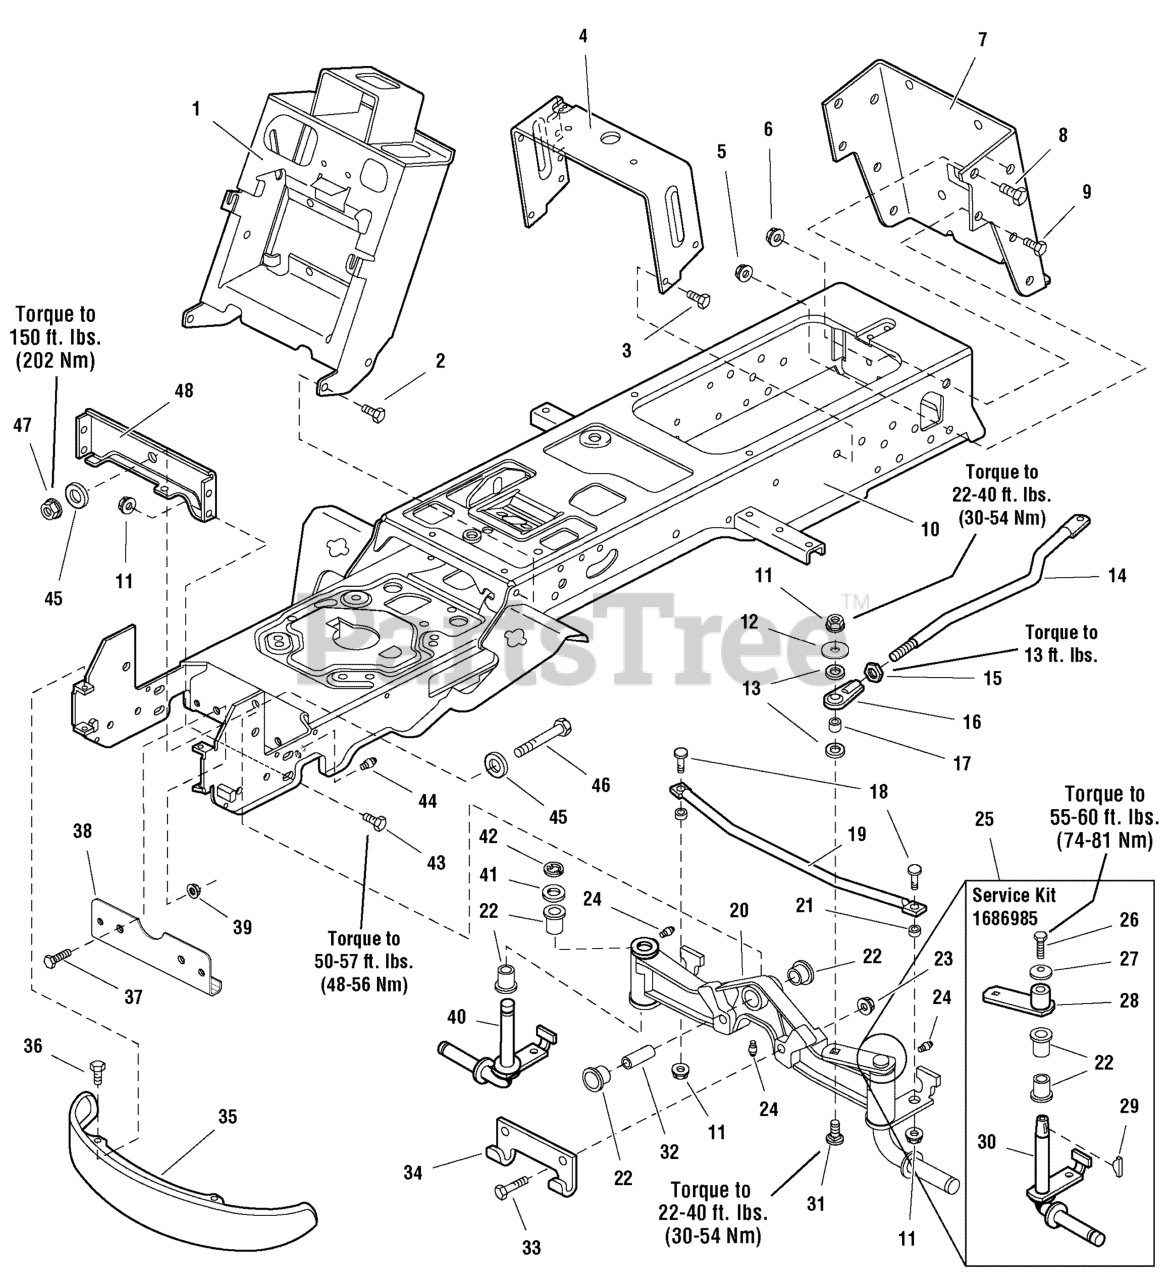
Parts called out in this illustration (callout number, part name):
1	TOWER & SUPPORT ASSEMBLY
2	CAPSCREW, Hex Washer Head, Taptite, 3/8-16 x 3/4
3	SCREW, Taptite, 5/16-18 x 3/4
4	SUPPORT, Seat Deck
5	NUT, Hex Flange Whiz Lock, 3/8-16 Large
6	NUT, Hex Flange, Two-Way Lock, 1/2-13
7	BACKPLATE, Hitch
8	CAPSCREW, Hex Head 1/2-13 x 1, Black
9	CAPSCREW, Hex Head, 3/8-16 x 1, G5
10	FRAME ASSEMBLY, Front & Rear
11	NUT, Hex Flange, Two Way Lock, 3/8-16
12	WASHER, Flat, 13/32
13	WASHER, 3/8"
14	LINK, Drag
15	NUT, Hex Head, 1/2-20, Black
16	JOINT-BALL .500-20 THD .500ID
17	SPACER, 0.377 x 1/2 x 5/8"
18	BOLT, Carriage, 3/8-16 X 1, G5
20	AXLE ASSEMBLY, w/ LH Spindle, Complete (Includes Ref. Nos. 22, 24, 41, 42 & 43)
21	SPACER, 3/8 ID x 5/8 OD x 5/16"
22	BUSHING, 31/32 x 1-1/4 x 3/4, Powder Metal
23	NUT, Hex Two Way, 7/16-14
24	FITTING, Grease
25	SPINDLE REPLACEMENT KIT, LH (Includes Ref. Nos. 22, 26, 27, 28, 29 & 30)
26	CAPSCREW, Hex Hd., 3/8-16 x 7/8, Gr. 8
27	WASHER, Spring, 3/8
28	HUB & ARM ASSEMBLY
29	KEY, Hi-Pro, 1/4 x 3/4
30	SPINDLE, LH
31	BOLT, Carriage, Short Neck, 3/8-16 x 1-1/2
32	SPACER, 0.641ID x 0.978OD x 2.082LG
33	CAPSCREW, Hex Head, 7/16-14 x 2, G8, Black
34	HOOK, Mower, Hitch
35	BUMPER, Black, Steel, Standard
35	WASHER, 1, (As Required for All Front, As Required for K62 Rear)
36	SCREW, Truss Head Torx, 5/16-18 x 7/8
37	SCREW, Hex Flange Whiz Lock, 3/8-16 x 3/4
38	FITTING, Grease
39	WASHER, 5/8
40	SPINDLE ASSEMBLY, RH
41	WASHER, 1, (As Required for All Front, As Required for K62 Rear)
42	RING, Retainer
43	SCREW, Hex Flange Whiz Lock, 3/8-16 x 3/4
44	FITTING, Grease
45	WASHER, 5/8
46	CAPSCREW, Hex Head, 5/8-11 x 3-1/2, GR5
47	NUT, Hex Flange, 5/8-11
48	PLATE, Axle Support
